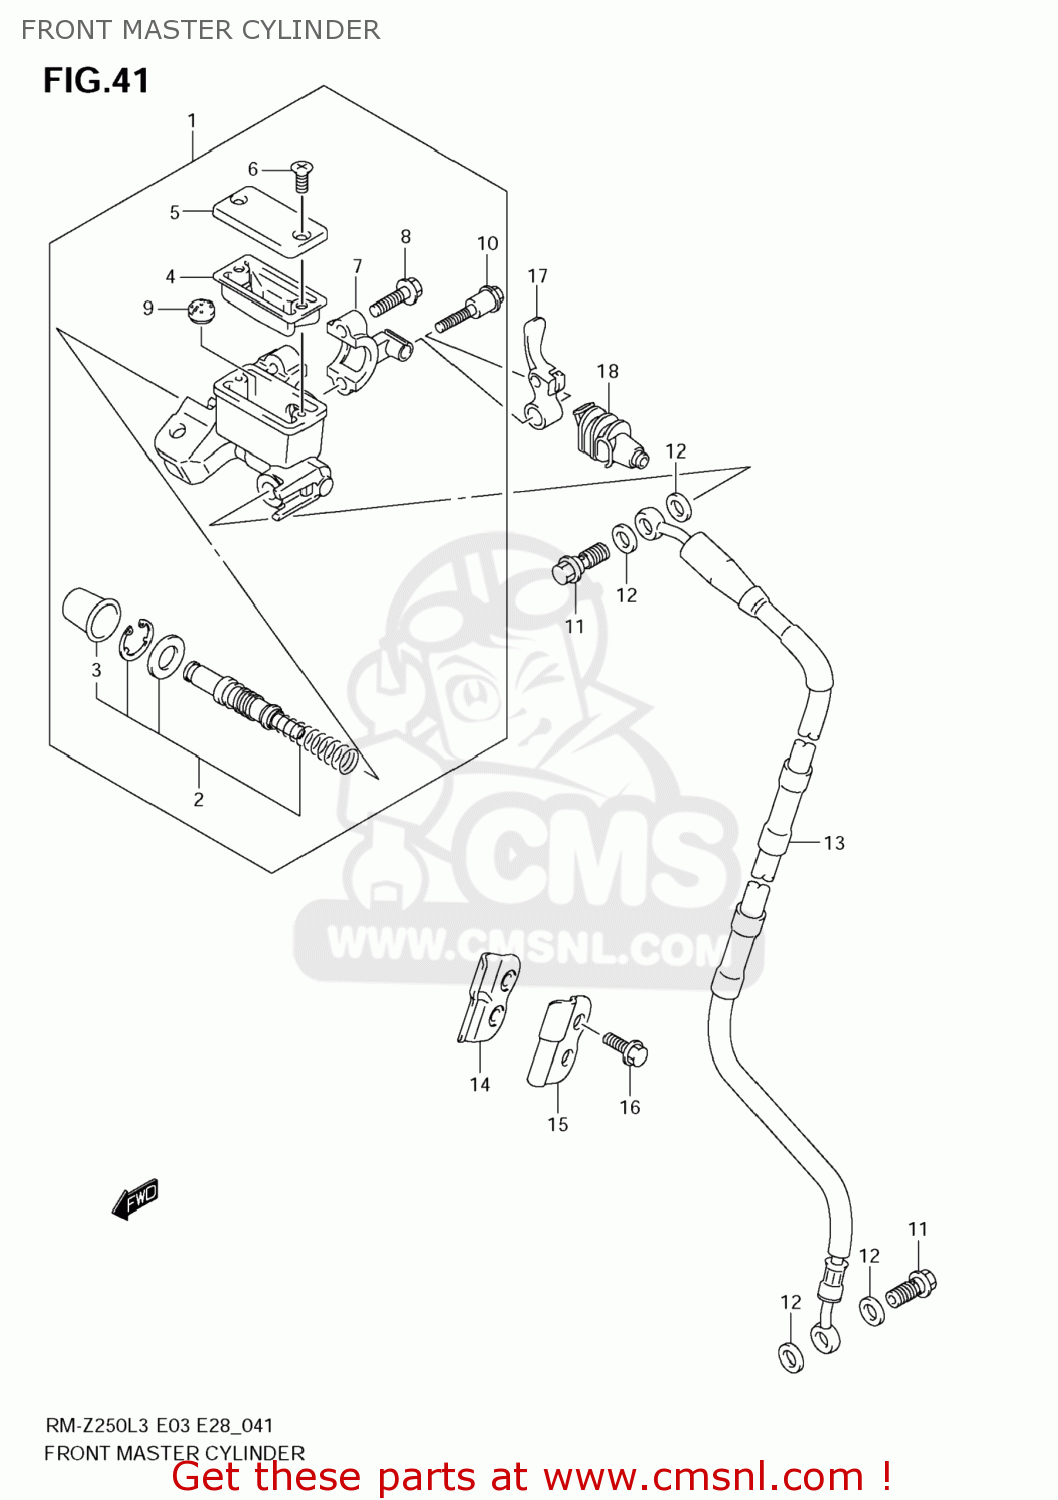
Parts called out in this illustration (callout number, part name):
1	CYLINDER ASSY,FR MASTER
2	PISTON & CUP SET
3	BOOT
4	DIAPHRAGM
5	CAP
6	SCREW
7	HOLDER
8	BOLT
9	SEPARATOR
10	BOLT,MASTER CYLINDER HOLDER
11	BOLT UNION
12	WASHER(10X15X1.5)
13	HOSE,FR BRAKE
14	CLAMP,FR BRAKE HOSE INNER
15	CLAMP,FR BRAKE HOSE
16	BOLT(6X16)
17	LEVER,MASTER CYLINDER HOLDER
18	COVER,MASTER CYL HOLDER LEVER
